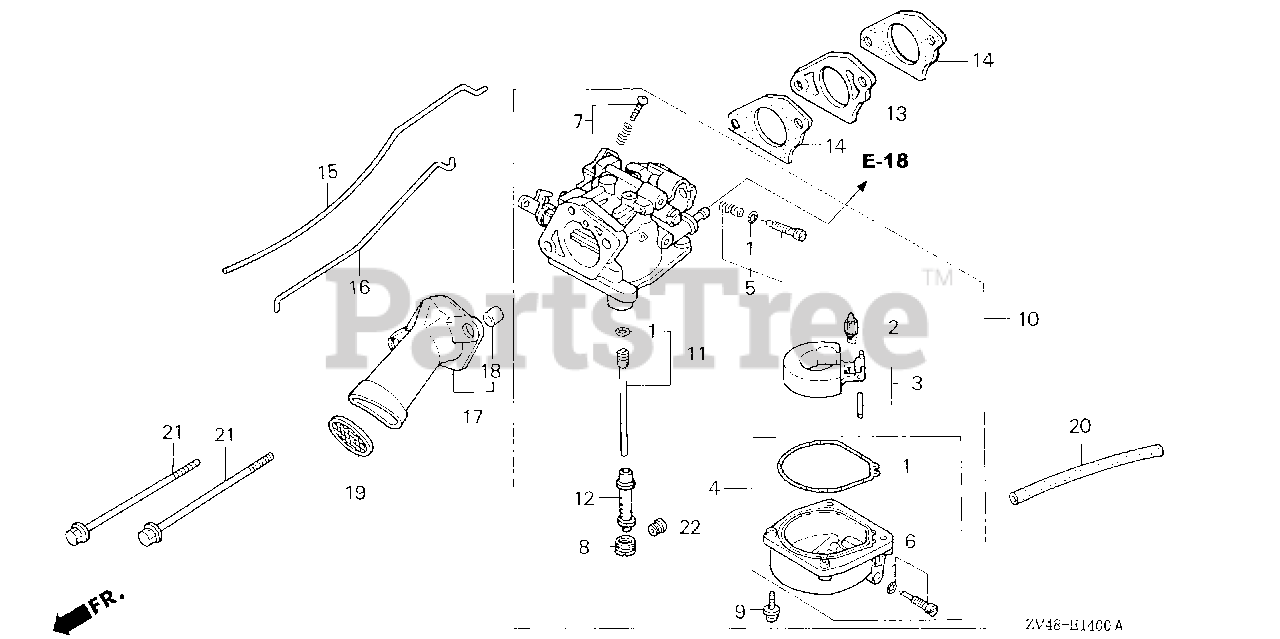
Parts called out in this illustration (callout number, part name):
1	GASKET SET
2	VALVE SET, FLOAT
4	CHAMBER SET, FLOAT
6	SCREW SET, DRAIN
8	SCREW, PLUG
9	SCREW-WASHER
10	CARBURETOR ASSY. (BG06F A)
11	JET SET (#52)
12	NOZZLE, MAIN
13	INSULATOR, CARBURETOR
14	GASKET, CARBURETOR
15	ROD, THROTTLE
16	ROD, CHOKE
17	GUIDE, AIR
18	COLLAR, DISTANCE
19	TRAP, FLAME
20	BULK HOSE, VINYL (3.5X6.5X8000) (3.5X6.5X100)
21	BOLT, FLANGE (6X95)
22	JET, MAIN (#102)
22	JET, MAIN (#105)
22	JET, MAIN (#108)
